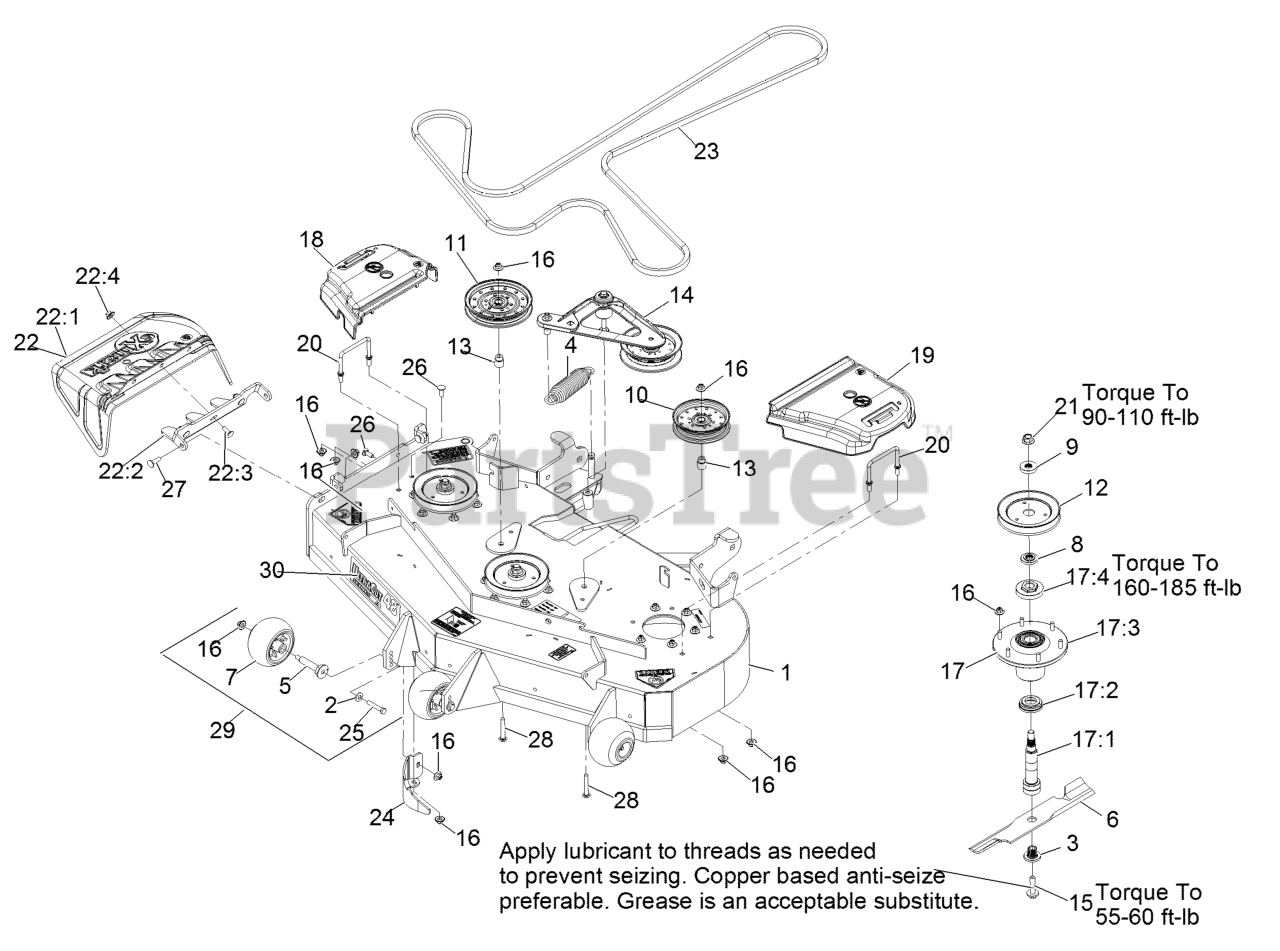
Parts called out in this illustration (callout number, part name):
1	ASM,DECK W/DECALS 48
2	WASHER-BELLEVILLE
3	BUSHING,SPLINED
4	SPRING-EXTENSION
7	ROLLER-SCALP, ANTI
8	SPACER,SPLINED STEPPED
9	SPACER,SPLINED
12	SHEAVE,BLADE DRIVE 5.90
13	BUSHING-IDLER
14	DECK IDLER ASM
15	SCREW,SEMS 1/2-20 X 2.19
16	Nut-Nyloc 3/8-16 Flg
17	ASM,SPINDLE HOUSING
17:1	GUARD,BOTTOM
17:2	ASM,CUTTER HOUSING
17:3	NUT, SPINDLE 7/8-14
17:4	SPINDLE,DOUBLE SPLINE
18	COVER-BELT, RH
19	COVER-BELT, LH
20	WIREFORM-COVER
21	NUT-FLANGE, CENTERLOCK
22	ASM,DISCHARGE CHUTE
22:1	CHUTE,DISCHARGE
22:2	BRACKET,DISCHARGE CHUTE
22:3	SCREW-CARR
22:4	Nut-Nyloc 3/8-16 Flg
23	BELT
24	BAFFLE-DOGLEG,LZS LZX VT4
25	SCREW-HH
26	SCREW-CARR
27	Bolt-Carriage 3/8-16 X 1 1/4
28	SCREW-CARR
30	DECAL,ULTRACUT 48 SERIES
